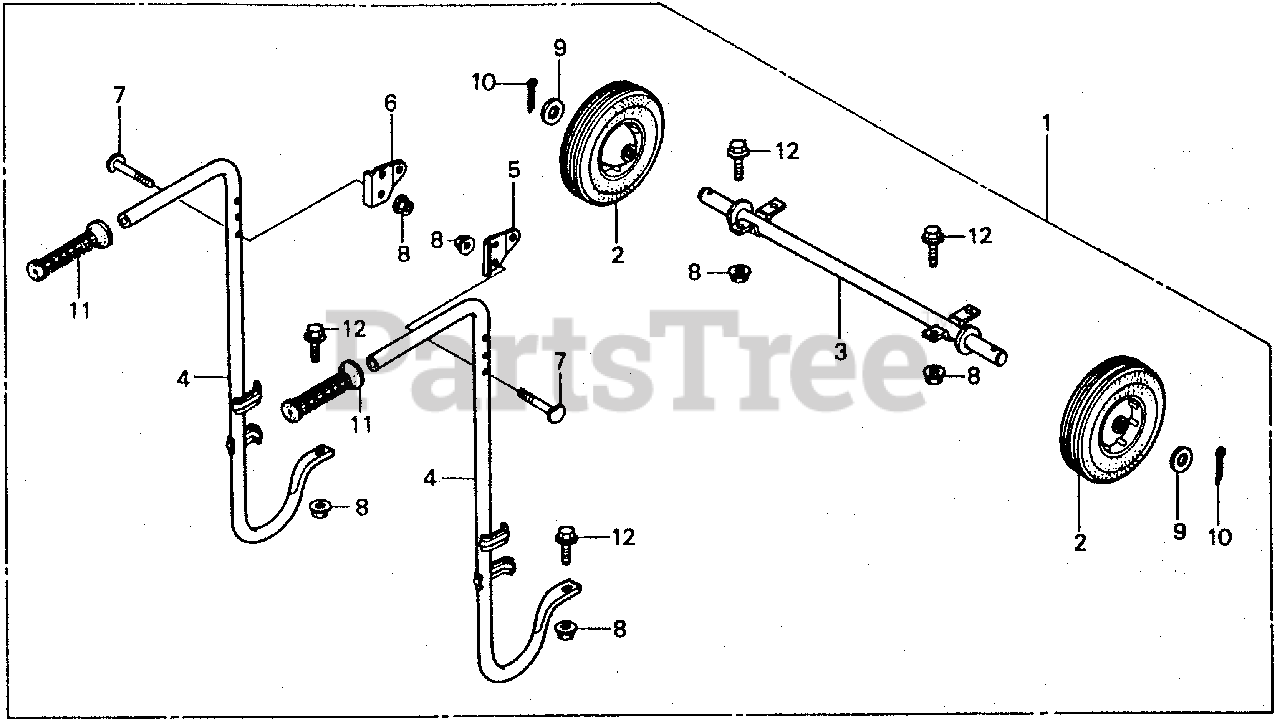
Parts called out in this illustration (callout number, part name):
1	WHEEL KIT (2-WHEEL)
2	WHEEL (10"X2.75")
3	SHAFT, WHEEL
4	HANDLE, CARRY
5	HOLDER, R. HANDLE
6	HOLDER, L. HANDLE
7	BOLT, HANDLE HOLDER
8	NUT, FLANGE (8MM)
9	WASHER, FLAT (20MM)
10	PIN, COTTER (4.0X30)
11	GRIP, R. HANDLEBAR
